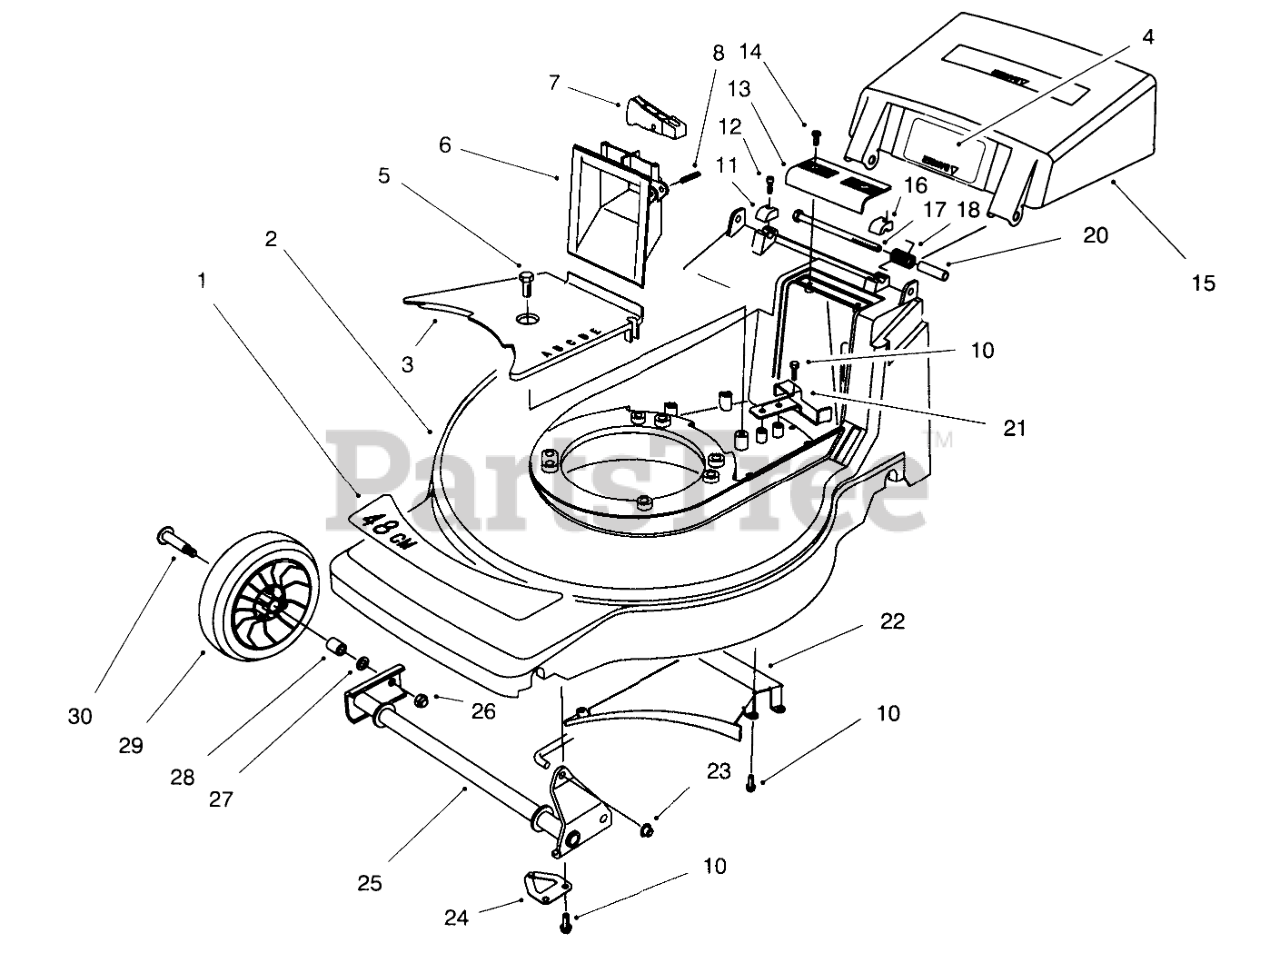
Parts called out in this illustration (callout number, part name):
1	DECAL - DECK 48 CM
2	HOUSING W/DECAL RED
3	BELT COVER
4	DECAL-DANGER
5	SCREW-HWHTF
6	GRIP - LOWER
7	TRIGGER - HOC
8	PIN-SPIRAL
10	SCREW-HWH
11	CAP-HINGE BOLT, RH
12	SCREW-HSH
13	GRIP-UPPER
14	SCREW-PPH, PLASTITE
15	Door Discharge
16	CAP-HINGE BOLT, LH
17	SCREW-HH
18	SPRING-DOOR
20	SPACER-DOOR
21	REAR BELT GUIDE
22	Ramp-Discharge
23	NUT-PUSH
24	SHAFT RETAINER ASM
25	FRONT PIVOT WA
26	NUT-HEX
27	WASHER
28	BUSHING
29	Wheel & Tire Assembly (Incl. Ref. #28)
30	BOLT-WHEEL
